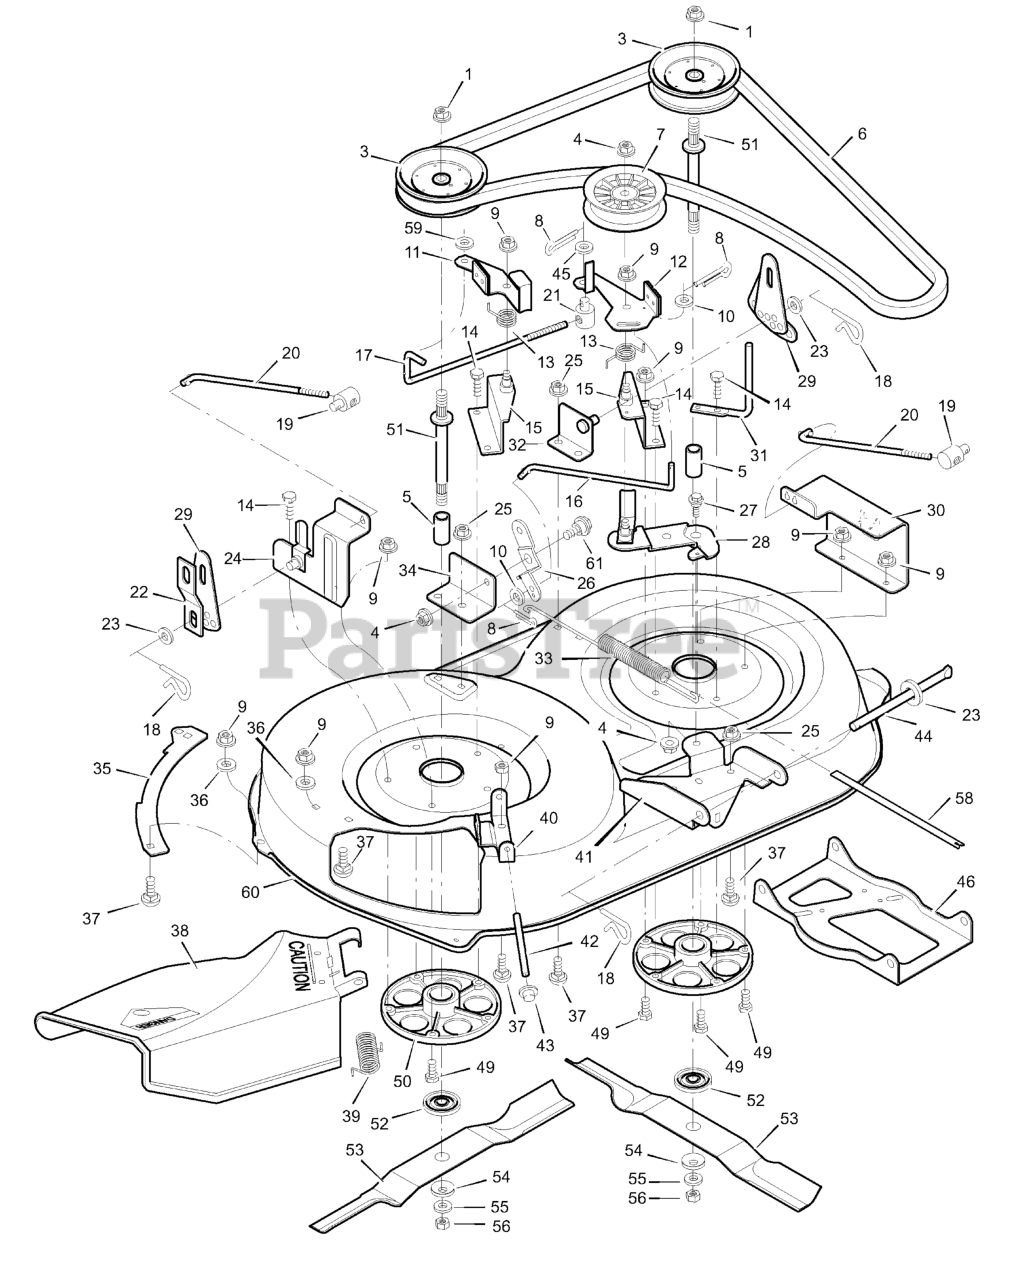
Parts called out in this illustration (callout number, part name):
1	Nut, Hex
3	Pulley, Jackshaft
4	Locknut, Flange
5	Spacer
6	Belt, Blade Drive
7	Pulley, Idler
8	Pin, Cotter
9	Locknut, Flange
11	Brake Assembly, Right
12	Brake Assembly, Left
13	Spring, Torsion
14	Bolt, Hex
15	Bracket Assembly, Brake
16	Rod, Brake
17	Rod, Cross Link
18	Pin, Hair
19	Nut, Adjustable
20	Rod, Adjuster
21	Nut, Adjustable
22	Link, Suspension
24	Bracket Assembly, Right Lifter
25	Nut, Flange
26	Bracket, Pivot
27	Bolt, Shoulder
28	Arm Assembly, Idler
29	Plate, Adjuster
30	Cover, Pulley
31	Guide, Belt
32	Bracket Assembly, Left Lifter
33	Spring, Extension
34	Bracket, Pivot
35	Plate
37	Bolt, Carriage
38	Deflector Assembly, Chute
39	Spring, Torsion
40	Bracket, Hinge
41	Bracket, Front Hanger
42	ROD, Deflector
43	Cap, Push On
44	Rod, Hanger
46	Hanger, Front
49	CAPSCREW, Hex Head, 5/16-18 x 1
50	Housing, Jackshaft
51	Jackshaft
52	Adapter, Blade
53	Blade, 38" (2 required)
53	Blade, 40" (2 required)
54	Washer, Belleville
56	Nut, Hex
58	Indicator, Plastic
60	Housing, Blade (38")
60	Housing, Blade (40")
61	Bolt, Shoulder
